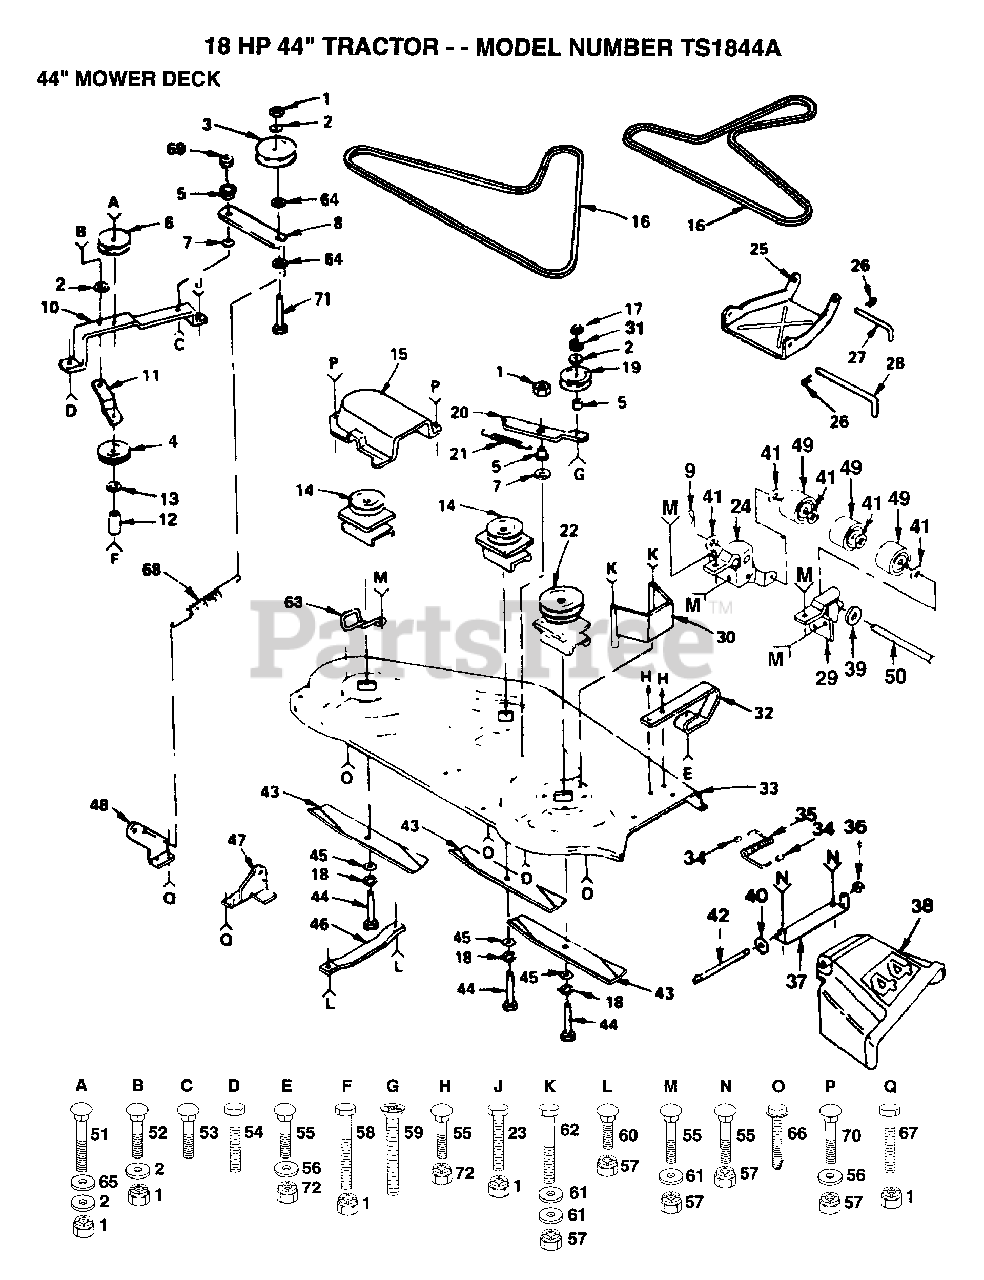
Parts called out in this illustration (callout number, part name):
2	WASHER
3	PULLEY IDLER
4	IDLER-FLAT T
5	SPACER RETAINER
6	IDLER-INSIDE T
7	"WASHER, WEAR LT"
8	ARM IDLER
9	COTTER PIN
10	"SUPPORT YT, BAR"
11	BRACE-IDLER YT
12	SPACER
13	WASHER
15	GUARD YT
16	BELT-V.79.1.MWR
17	NUT.HEX.3/8-16UNC
19	IDLER.FLAT.GTV
20	ARM-IDLER YT
23	BOLT
24	BRACKET LH YTH
25	LINK.PARALLEL
26	SPRING.RETAINER
27	"ROD, FRT. PARAL T"
28	HINGE PIN T
29	BRACKET RH YTH
30	GUARD BELT HYT
31	LOCKWASHER
32	RUNNER.RH
34	CAP-SLEEVE LT
36	NUT PUSH M
37	BRKT DEFLECTOR
38	DEFLECTOR SHIELD
40	WASHER
41	WASHER T
42	ROD-HINGE T
44	BOLT.3/8-24X1-1/2
45	WASHER
46	RUNNER-LH M
47	BRKT SUSP REAR RH
48	BRKT SUSP REAR LH
49	ROLLER T
50	PIVOT PIN T
51	BOLT
53	BOLT
55	BOLT
56	WASHER
58	BOLT - HEX 3/8 - 16 X 3
59	SCREW YT
60	BOLT
61	WASHER M
62	BOLT
63	BELT RETIANER
64	WASHER
65	WASHER
66	SCREW
67	BOLT
68	"SPRING.EXT.8.5"""
69	LOCKNUT
71	BOLT
